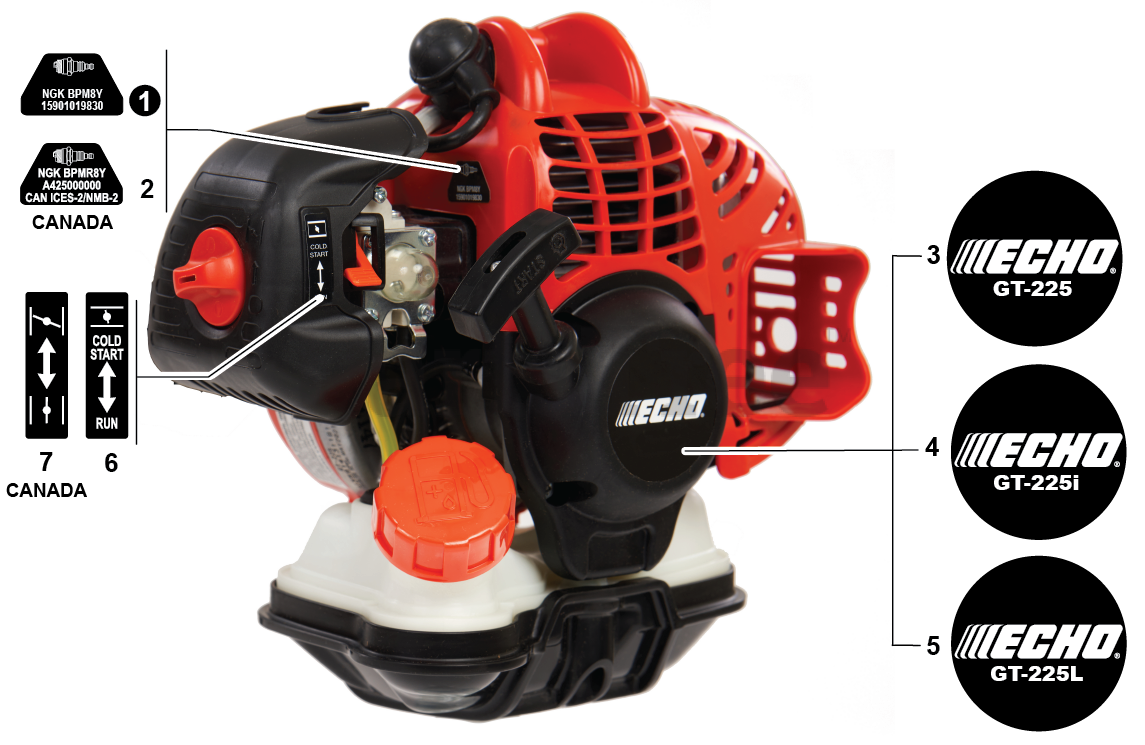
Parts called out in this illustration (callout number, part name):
1	LABEL - SPARK PLUG - BPM8Y
2	LABEL - SPARK PLUG - BPMR8Y
3	LABEL - STARTER - GT-225
4	LABEL - STARTER - GT-225I
5	LABEL - MODEL - GT-225L
6	LABEL - CHOKE
7	LABEL - CHOKE
